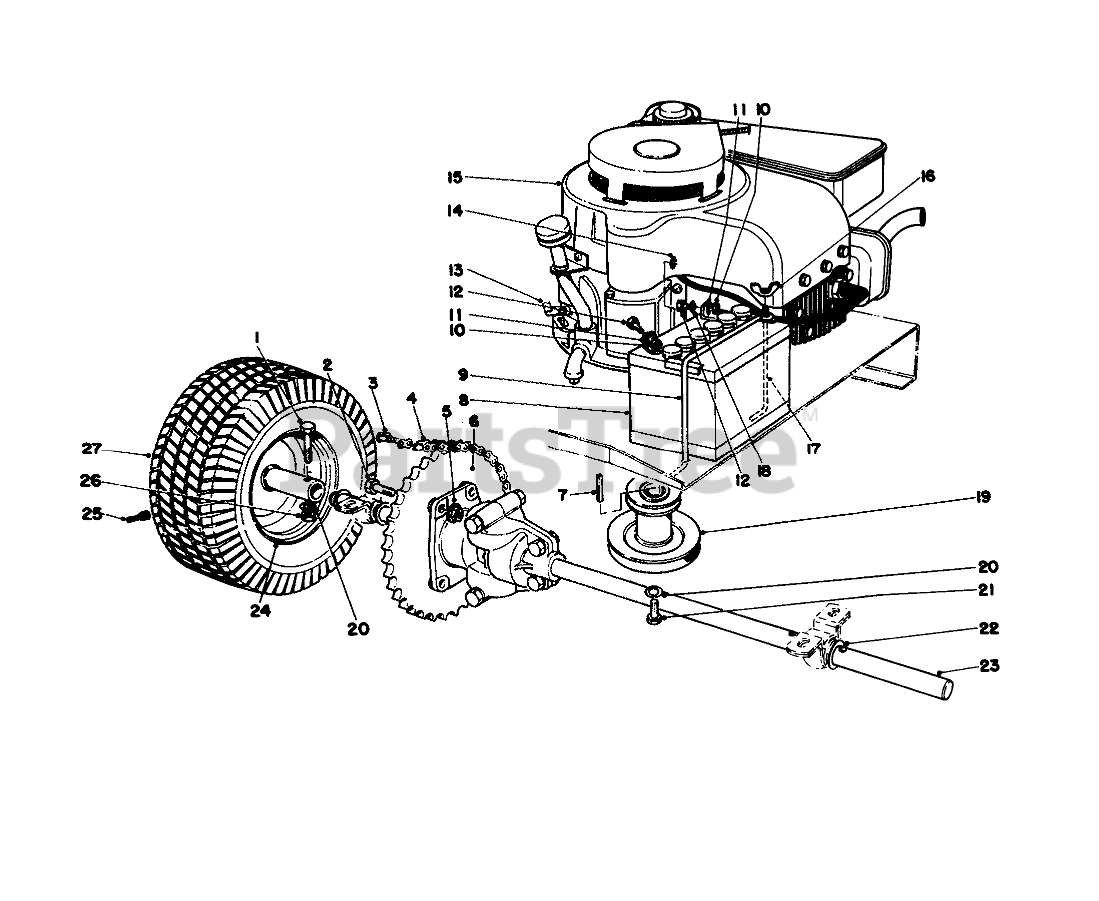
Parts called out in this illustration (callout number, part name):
1	SCREW-HH
2	SCREW-HH
3	LINK-CONNECTING
4	Chain-Roller
5	NUT-LOCK, CONE
6	Sprocket
8	BATTERY
9	Battery Clamp
10	NUT-HEX
11	WASHER-LOCK
12	SCREW-HH
14	WASHER-LOCK/EXT
15	Engine
16	NUT-WING SPECL
17	ROD-SUPPORT, BATTERY
18	WASHER-FLAT
19	Engine Pulley
20	WASHER-LOCK
21	SCREW-HH
22	WASHER
23	Differential
25	STEM-VALVE
26	NUT-LOCK, CONE
27	Tire
